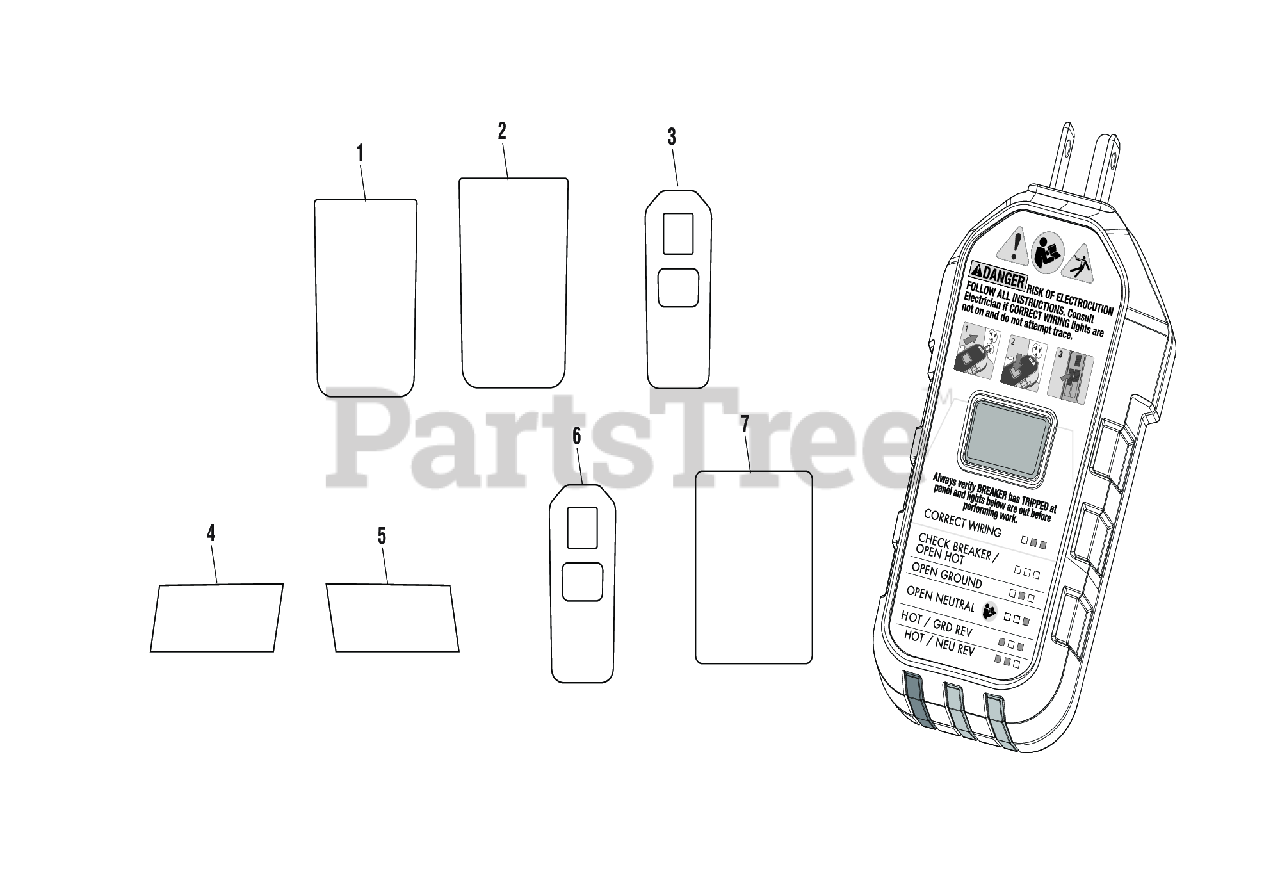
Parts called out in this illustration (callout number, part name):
1	Instructions Label - Back (French/Spanish)
2	Instructions Label - Back (English)
3	Instructions Label - Front (English)
4	Logo Label (Left)
5	Logo Label (Right)
6	Instructions Label - Front (French/Spanish)
7	Danger Hangtag
